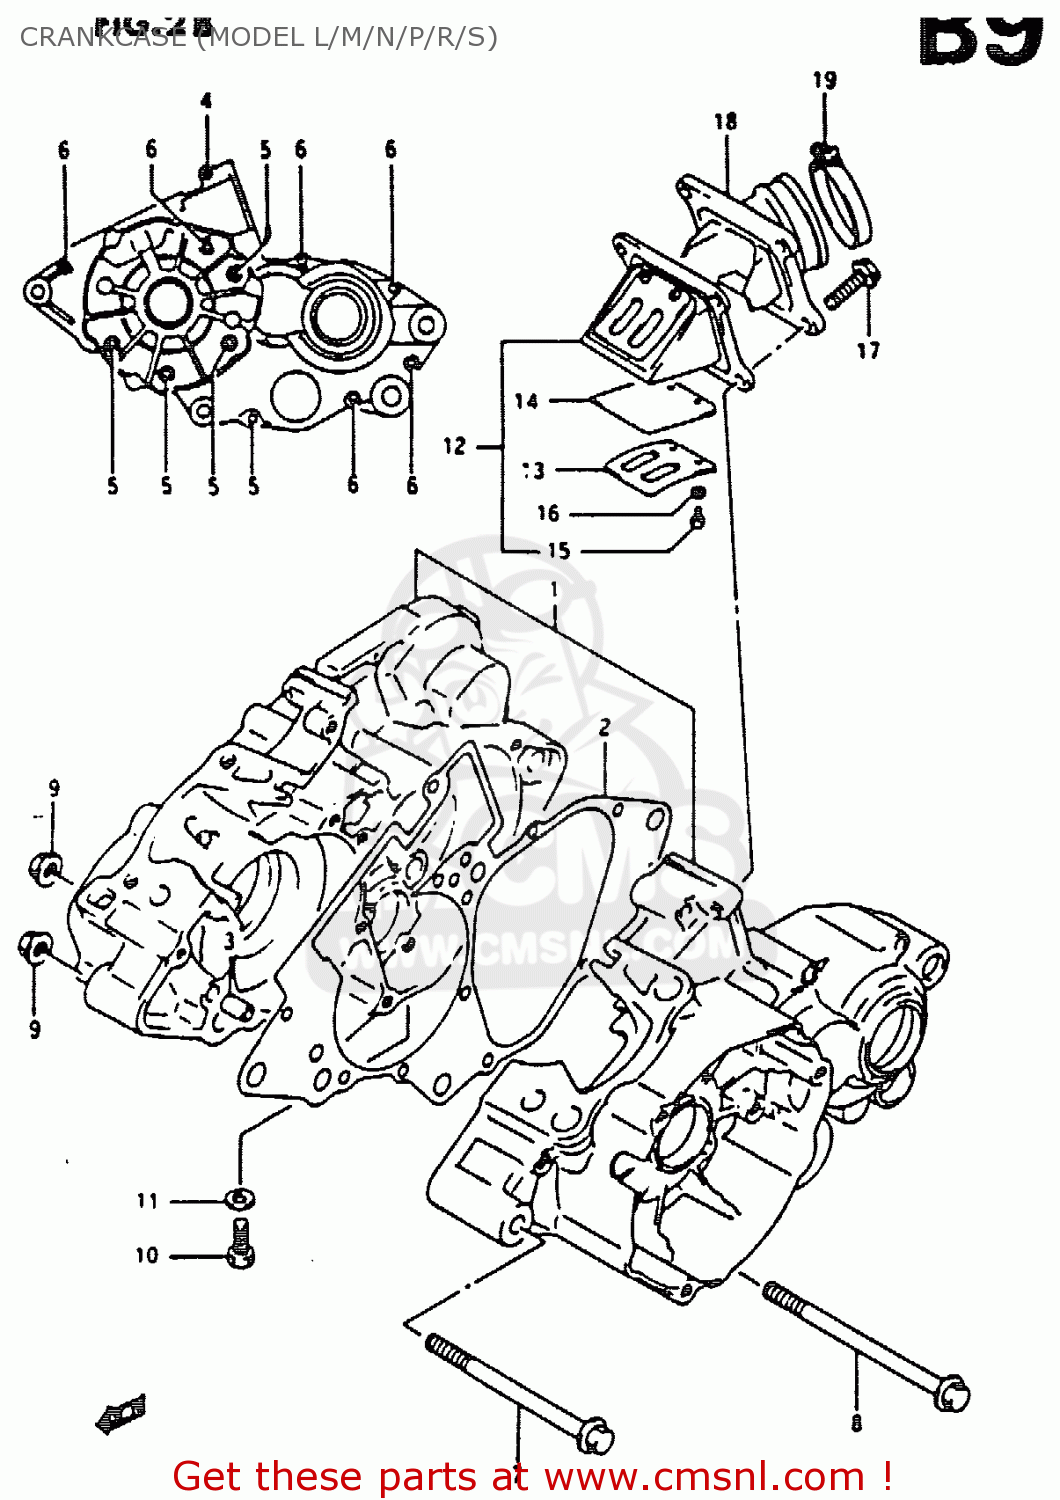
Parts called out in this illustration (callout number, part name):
1	CRANKCASE SET
2	GASKET,CRANKCASE (NAS)
3	PIN
4	BOLT
5	BOLT
6	BOLT
7	BOLT 8X92
8	BOLT(8X102)
9	NUT
10	BOLT
11	GASKET (NAS)
12	VALVE ASSY,REED
13	STOPPER,REED VALVE
14	VALVE,REED
15	SCREW
16	WASHER,LOCK
17	BOLT
18	PIPE,INTAKE
19	CLAMP
